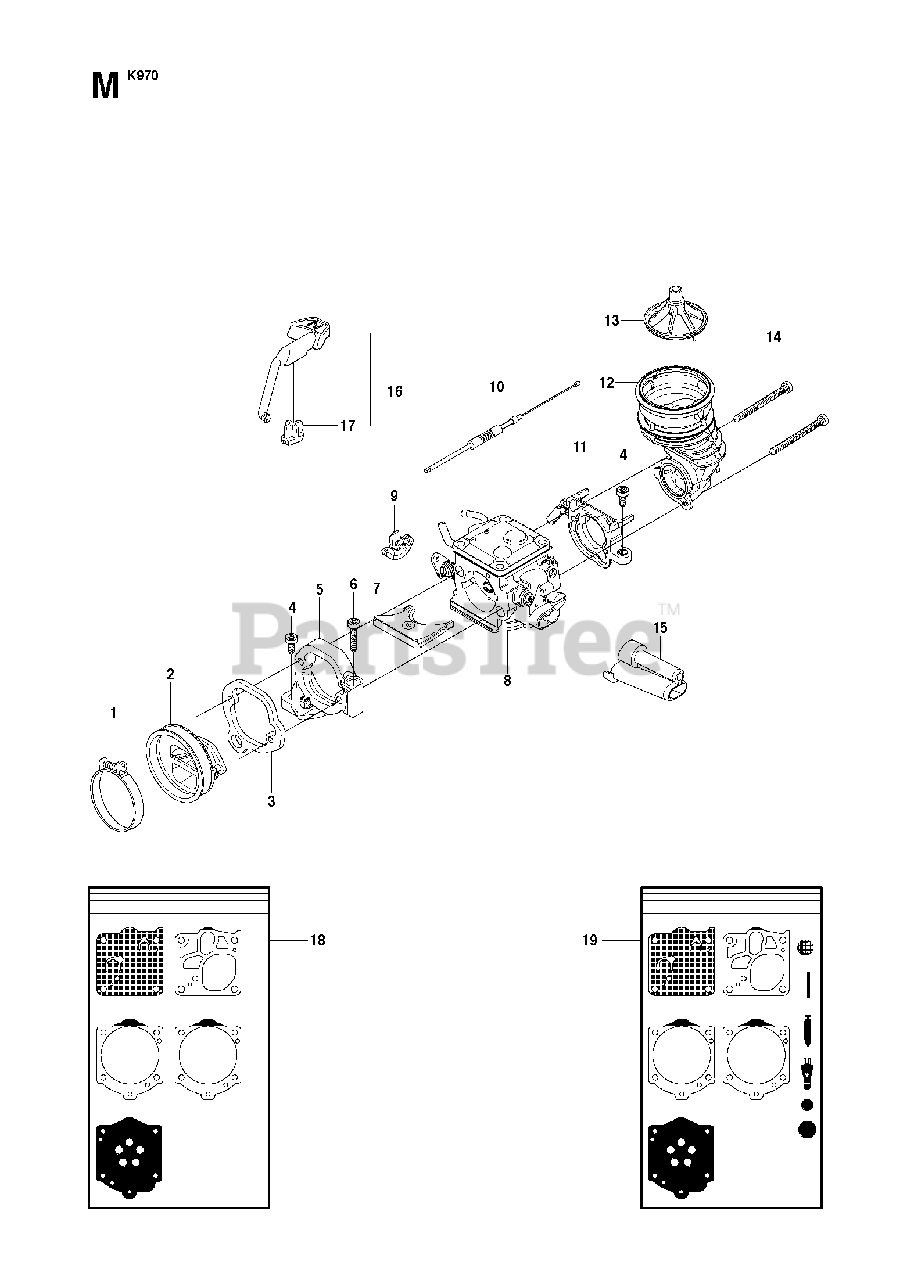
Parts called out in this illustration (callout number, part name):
1	HOSE CLAMP
4	SCREW ITXSCM
6	SCREW ITXSCM
8	CARBURETTOR
10	THROTTLE CABLE ASSY
11	FLANGE INLET PIPE
14	SCREW ITXSCM
15	CHISEL GUIDE
17	WEAR PROTECTION
19	REPAIR KIT
